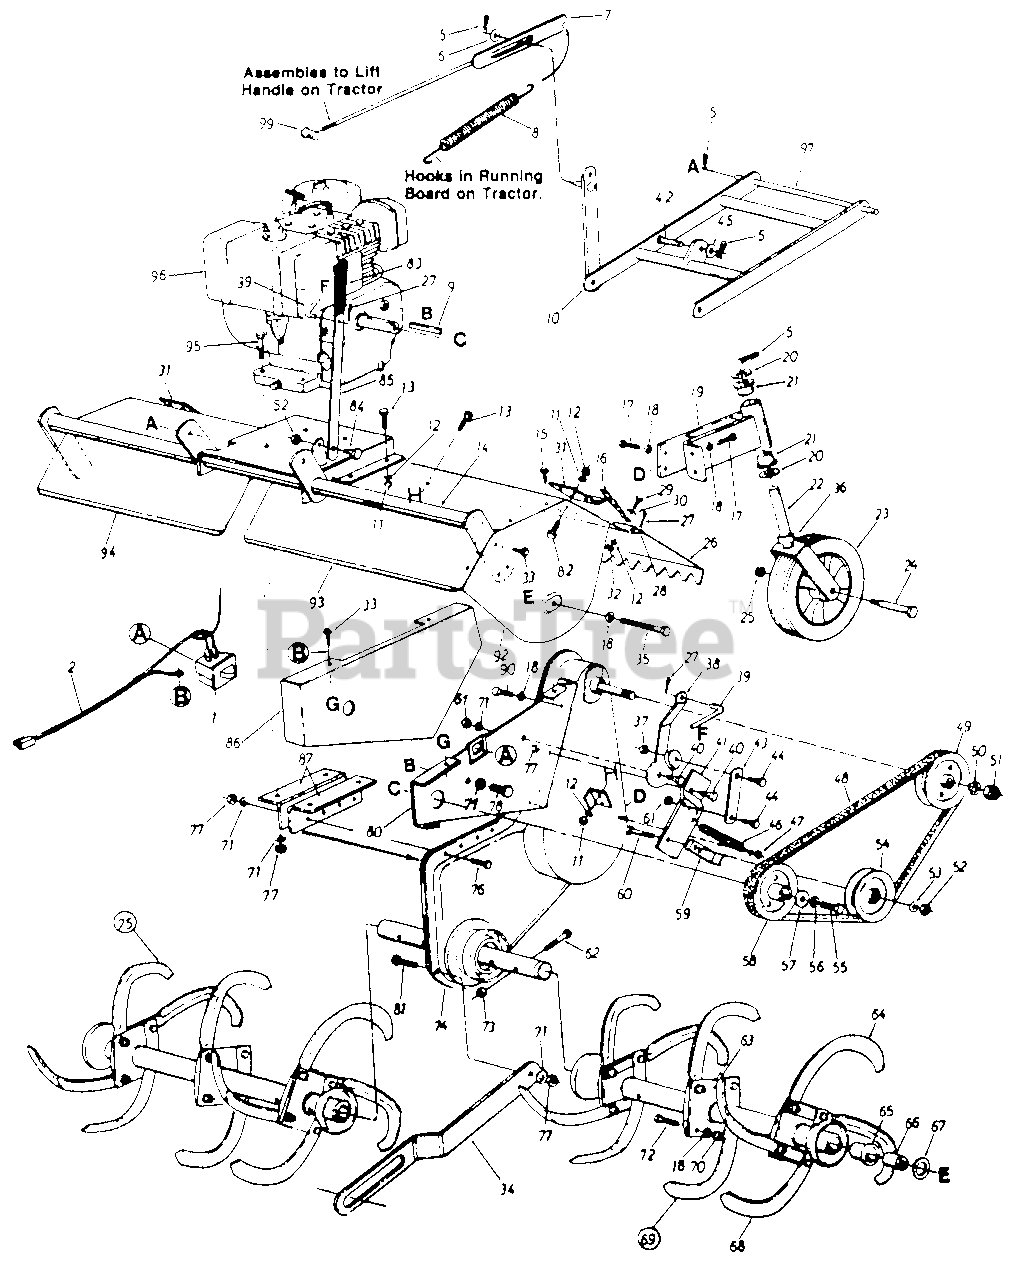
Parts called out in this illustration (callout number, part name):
1	Safety Switch
2	Wire Harness
5	Internal Cotter Pin
6	Fl-Wash. 1/2" I.D. x .93" O.D.
9	Sq. Key 1/4" X l/4" X 2.00" Lg.
12	L-Wash. I.D.'
13	Hex Bolt 28 x .62" Lg.
16	#2 Dog Chain x 20" Lg.
17	Hex Wash. Hd. Self-Tap Scr. 3/8-24 x .75" Lg.
18	L-Wash. 3/8" I.D.
21	Flange Bearing 3/.1" I.D. x 1.001' O.D.
24	Shoulder Bolt .623" I.D. x 3.62" Lg.
25	Hex Cent. L-Nut 7/16-14 Thd.
28	L.H. Flap Rod
29	Hex Bolt 1/4 20 x .62" Lg.
30	Fl-Wash. 1/4" I.D.
33	Hex Wash. Hd. Selt-Tap Scr. 1/4 " x .62" Lg.
36	Spacer.752" I.D. x 1.25" O.D.
37	Hex Cent. L-Nut 5/16-18 Thd.
40	Shoulder Bolt 7/16" Dla. x 1.75" L9.
45	Fl-Wash. .50 I.D. x 1.0 O.D. x .0
46	Extension Spring .62 O.D. x 6.12" Lg.
47	Hex Crown Nut 3/8-24 Thd.
48	"V"-Belt (Kevlar)
49	l/2" V-Pulley 4.75" O.D. x .625" Bore
50	L-Wash. 5/8' I.D.
51	Hex Ins. L-Nut 5/8-18 Thd.
52	Hex Cent. L-Nut 3/8-16 Thd.
53	Fl-Wash. 3/8" I.D.
54	Idler Pulley 4.0" O.D.
55	Hex Bolt
56	L-Wash. 7/16" I.D.
57	Fl-Wash. 7/16" I.D. x 1.38"
58	1/2" "V"-Pulley .475 O.D. x 1.00 Bore
61	Hex Cent. L-Nut 5/16-18 Thd.
62	Hex Bolt 7/16-14 x 2 00" Lg.
66	Spacer
67	Thrust Wash. 1/2 I.D. x 1.55"
71	L-Wash. 5/16" I.D.
72	Hex Bolt 3/8-24 x 1.5" Lg.
73	Hex Cent. L Nut 7/16-14 Thd.
77	Hex Nut 5/16-18 Thd.
78	Hex Bolt 5/16-24 x .62"
80	Clutch Support Bracket
81	Shld. Bolt .435 Dia. x .265 5/16-18 Thd.
82	Hex Bolt 1/4-28 x 75" Lg.
83	Plastic Grip
84	Shoulder Bolt .498 Dia. x .212 Lg.
96	8 H.P. Engine
97	Hitch Rod
99	Ferrule
